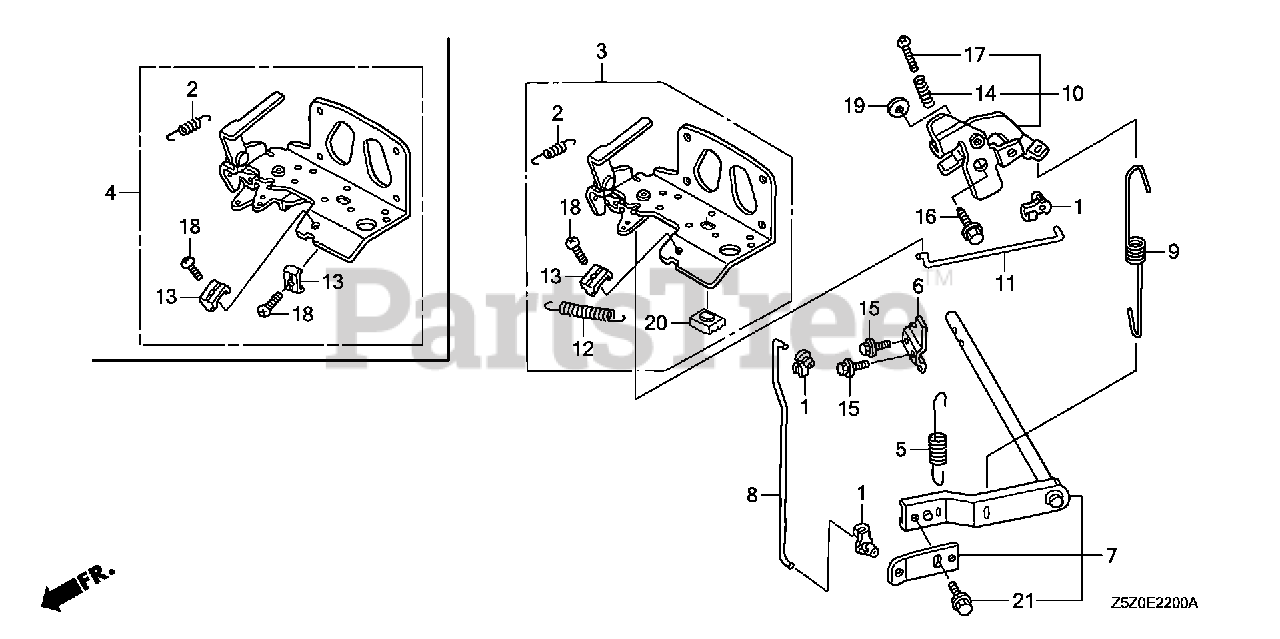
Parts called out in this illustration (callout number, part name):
1	ROD, JOINT
2	SPRING, CHOKE RETURN
3	CONTROL ASSY. (1-LEVER)
5	SPRING, STARTER
6	FORK, GOVERNOR
7	ARM, GOVERNOR
8	ROD, GOVERNOR
9	SPRING, GOVERNOR
10	LINK, GOVERNOR
11	ROD, GOVERNOR LINK
12	SPRING, LEVER
13	HOLDER, CABLE
14	SPRING, CONTROL ADJUSTING Use from Engine SN 2327377.
15	BOLT, FLANGE (5X10) Use from Engine SN 2327377.
16	BOLT, FLANGE (6MM) (CT200)
17	SCREW, RECESSED (5X25)
18	SCREW, PAN (5X16)
19	WASHER, PLAIN (6MM)
20	RUBBER A, STAND STOPPER
21	BOLT, FLANGE (6X10)
